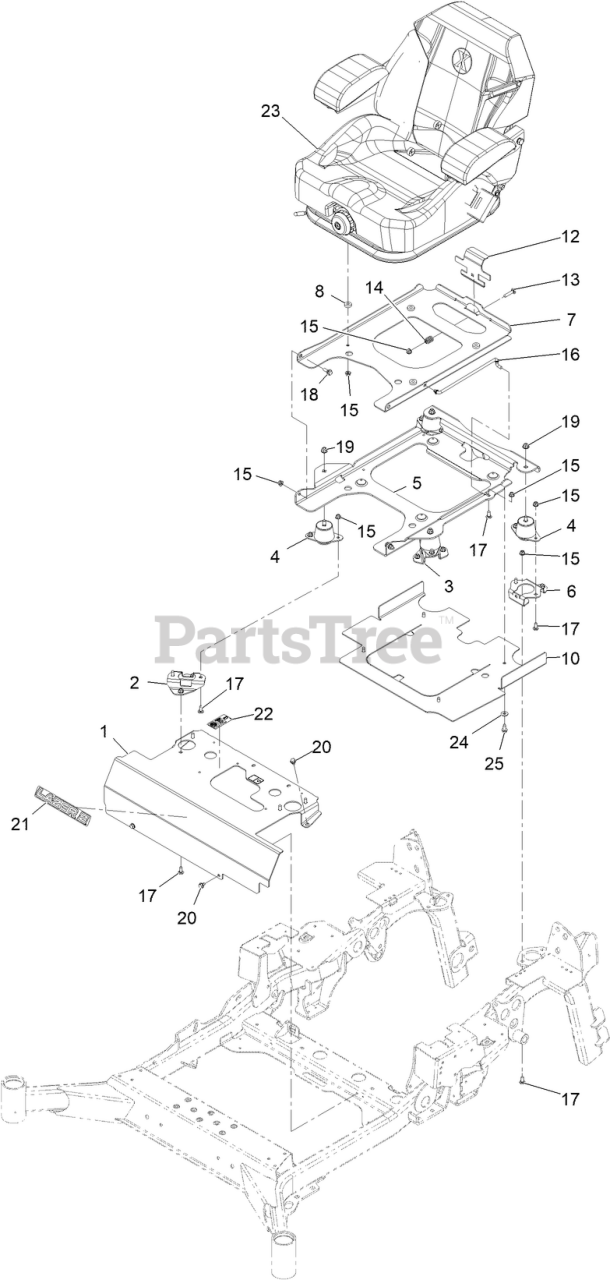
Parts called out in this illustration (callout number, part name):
1	MOUNT-SEAT W/DECALS
2	RISER-SEAT MOUNT, R
3	RISER-SEAT MOUNT, L
4	ISOLATOR-SEAT
5	PLATE,TILT SEAT SUPPORT
6	RISER-SEAT MOUNT, REAR
7	PLATE-FRAME, SEAT
10	SHIELD-HEAT
12	PLATE, SEAT LATCH
13	BOLT-CARR
14	SPRING-COMPRESSION
15	NUT-HF, NI
16	ROD-PROP
17	SCREW-CARR
18	SCREW-SHOULDER
19	NUT-HF, NI
21	DECAL, LAZER MODEL
22	DECAL-TRANS FLUID
23	ASM-SUSPENSION SEAT, EXMARK
24	WASHER-FLAT
25	Screw-HWH 5/16-18 X 3/4 Tf
